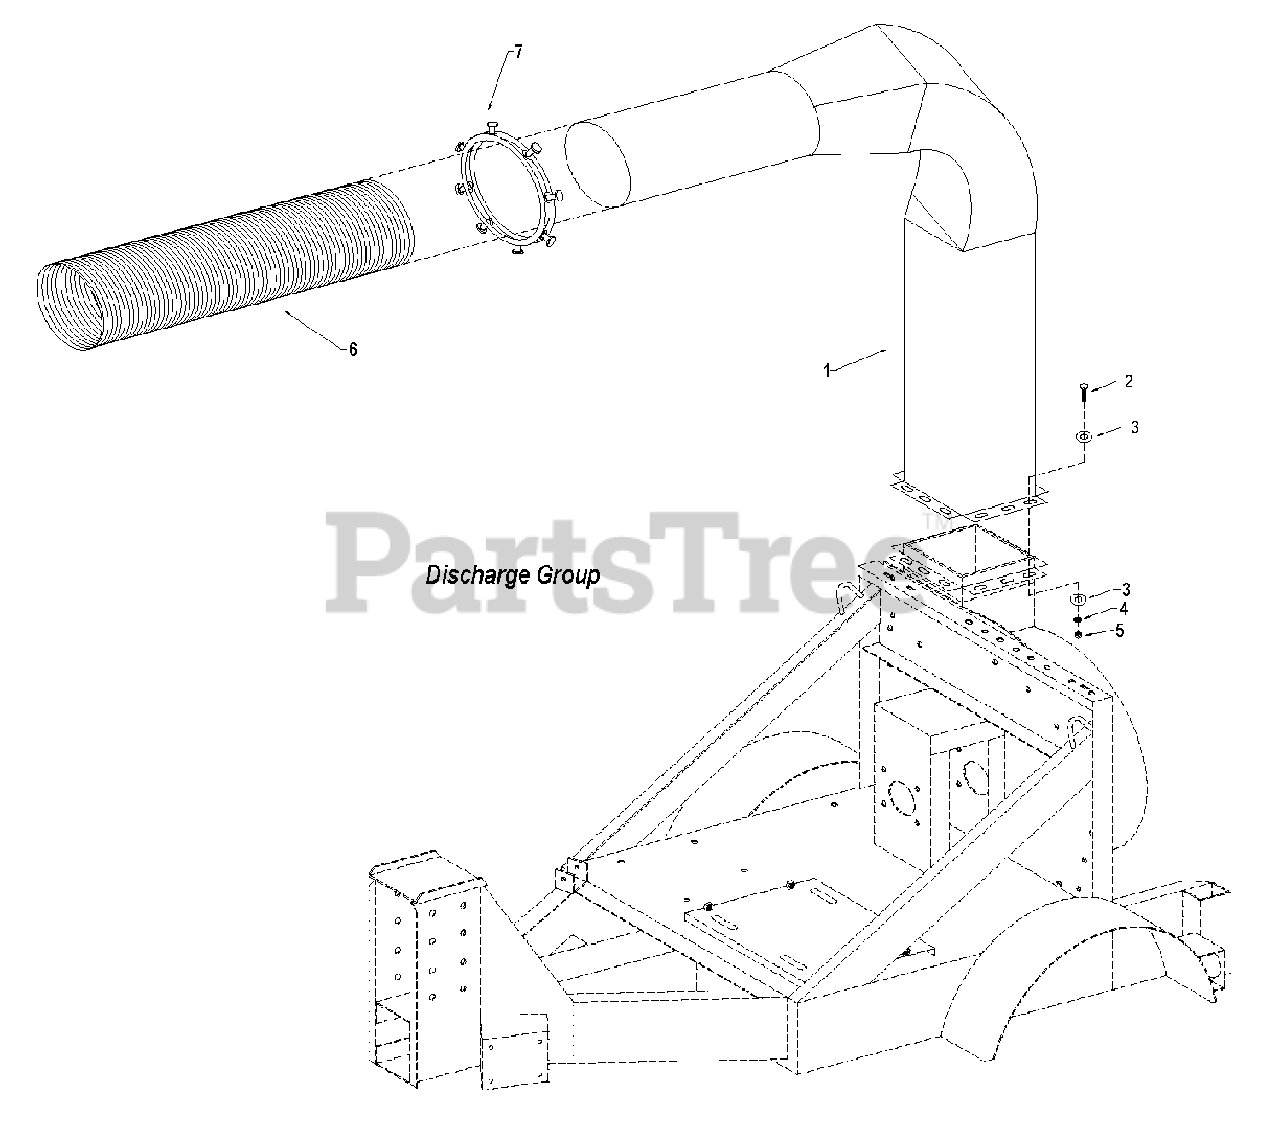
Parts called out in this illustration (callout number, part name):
1	Stack and elbow assy
2	Bolt, hex - 1/2-13 x 1-3/4"
3	Washer, flat - 1/2
4	Washer, lock - 1/2"
5	Nut, hex - 1/2-13
6	Hose, discharge - 12" x 6' metal
7	Ring, squeeze - 12"
